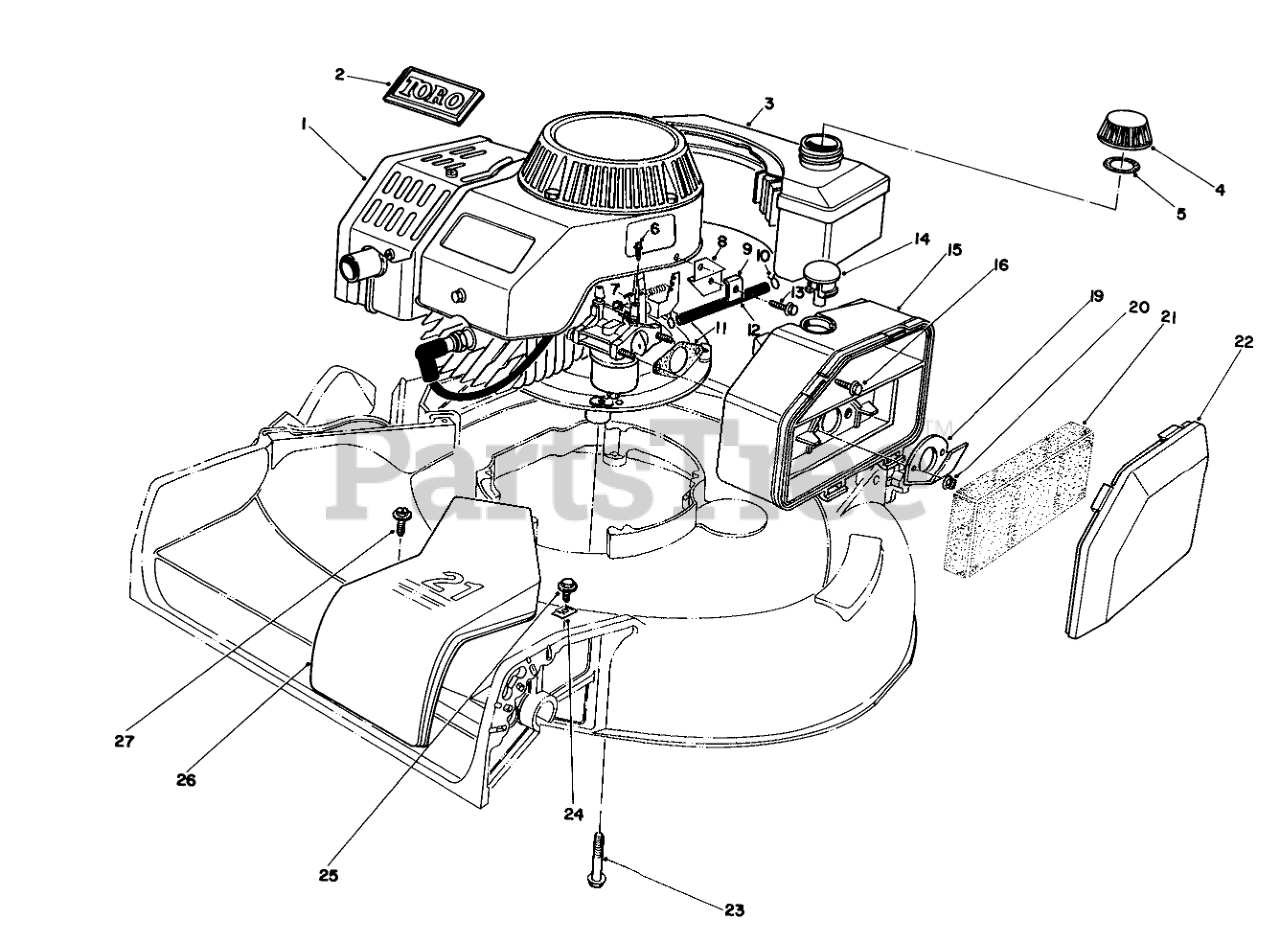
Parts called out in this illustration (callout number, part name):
1	Engine (Incl. Ref. #2)
2	TORO LOGO PLT
3	Fuel Tank Assembly
4	Gas Cap Assembly (Incl. Ref. #5)
5	GAS CAP GASKET
6	TAPPING SCREW
7	CHOKE LEVER
8	Carrier-Cable
9	CLAMP-CABLE
10	CLAMP-HOSE
11	GASKET-AIR CLEANER
12	FUEL LINE
13	Screw
14	Plug-Button
15	AIR CLEANER
16	Screw-Hex Head
19	SPIT BACK DEFLECTOR
20	M6 X 1 LOCKNUT
21	FILTER
22	AIR CLEANER COVER
23	FLG SCREW,3/8-16X2.000
24	Cable Clamp
25	SCREW-HWHTF
26	BELT COVER 21" S D
27	SCREW
